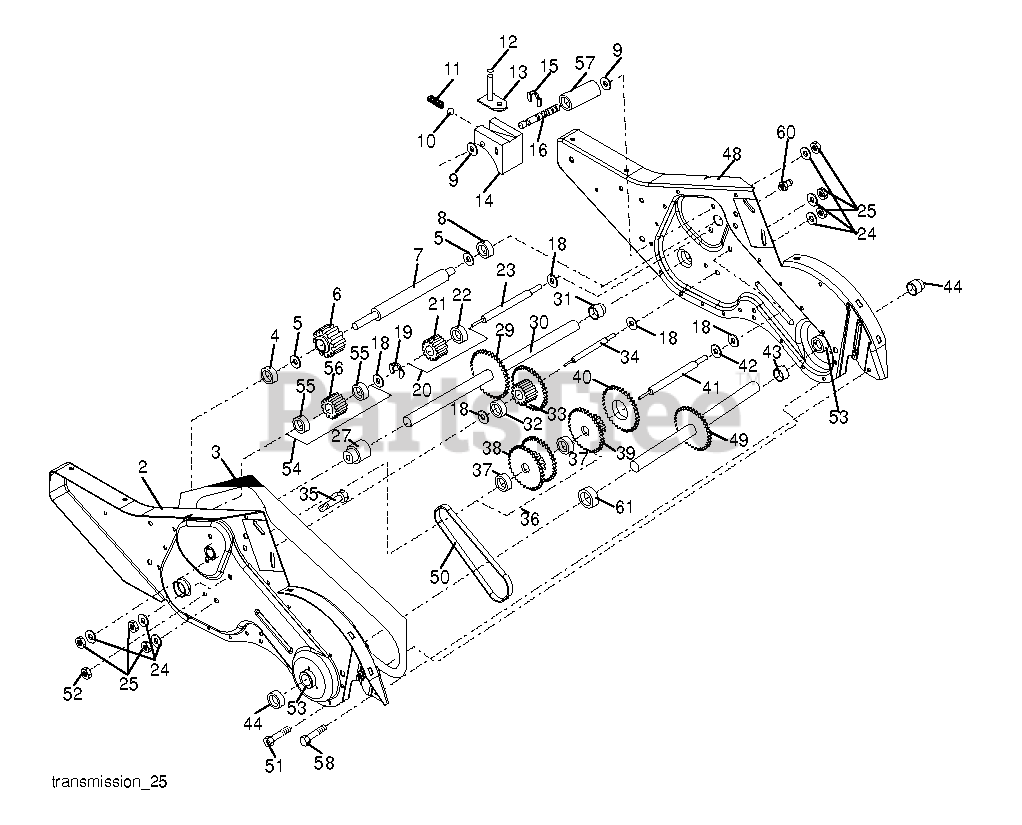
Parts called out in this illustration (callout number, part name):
2	GEARCASE.ASM.DRT.LH.
3	GASKET.GEARCASE.CRT/DRT.TILLER
4	NEEDLE BRNG LT
5	THRUST WASHER
6	PINION INPUT DRT TILLER
7	SHAFT.INPUT.D.9TEETH
9	WASHER, SEAL (2 2)
10	BALL, STEEL
11	SPRING-SHIFT CRT
13	BRACKET ASM.SHIFT.CRT
14	SHIFT FORK TI
16	SHAFT.SHIFT.DRT
20	GEAR ASSY CRT
21	GEAR-REV IDLR CRT
22	NEEDLE BEARING TI
23	SHAFT.IDLER.REVERSE.CRT
24	LOCKWASHER
25	NUT.ASF.HEX.7/16
27	BEARING.GROUND.DRIVE
30	GROUND SHAFT ASS'Y
31	BEARING, SHAFT RH CRT
33	SPRCKT 8 GEAR CRT
34	SHAFT.SECONDARY.REDUCTION.CRT
35	SCRW WHIZ LOK CRT
36	GEAR & SPROCKET.ASM.WBEARIN
37	BEARING.NEEDLE.CRT
38	ASM.GEAR & SPROCKET
39	GEAR.CLUSTER.DRT.TILLER
41	SHAFT.REDUCTION.FIRST.DRT
42	BRNG RACE T
44	SEAL ASM, OIL
48	GEARCASE.ASM.DRT.RH.
49	SHAFT.ASM.TINE
50	CHAIN.TILLER
51	SCREW
52	NUT
53	KIT.BEARING.TILLER.
54	GEAR.ASM.DRT.TILLER
55	BEARING.NEEDLE
56	GEAR.DRT.IDLER
57	SPACER.SPLIT
58	BOLT SHOULDER 1/4-20 UNC X.875
60	FITTING.GREASE.TAPERED
61	SPACER.1.015X1.50X.650
